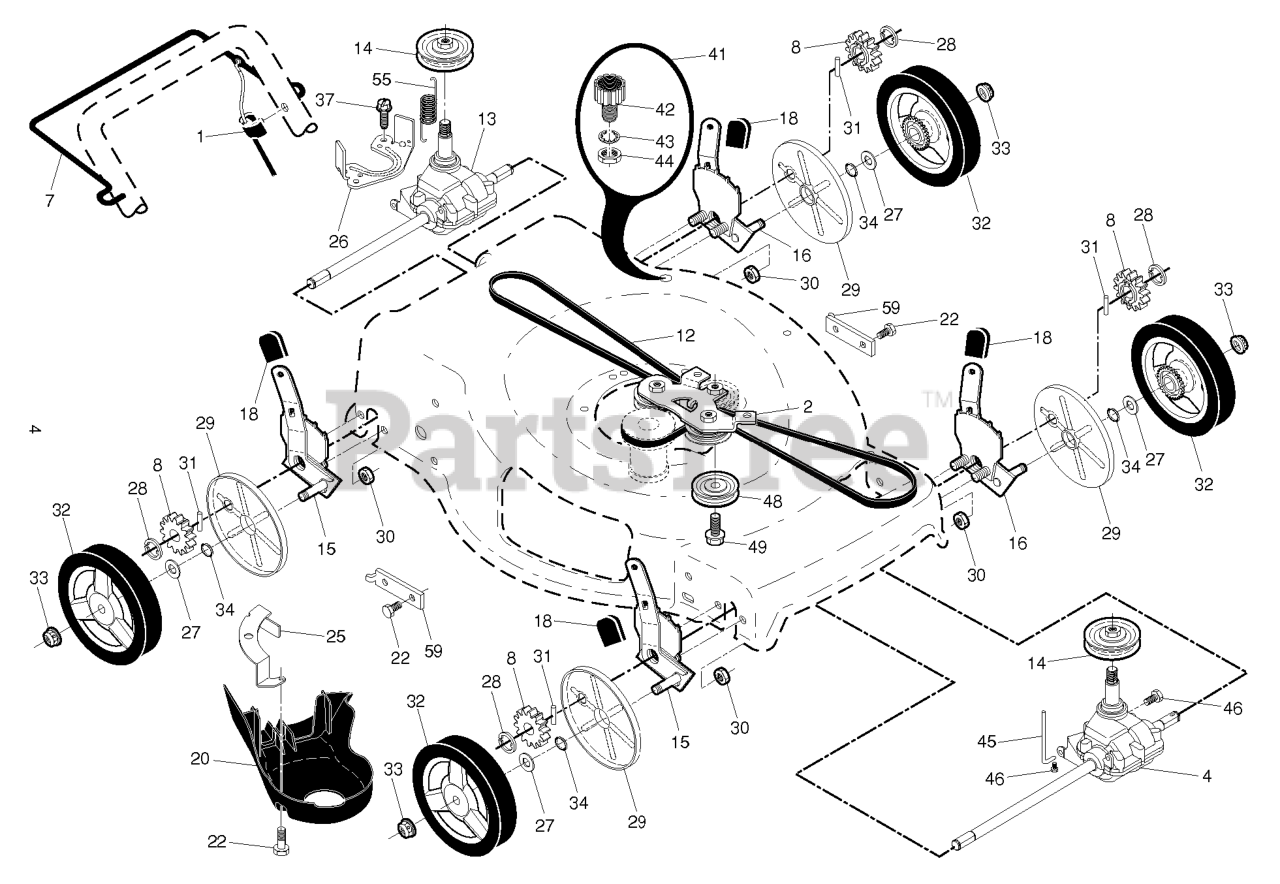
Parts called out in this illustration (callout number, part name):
1	CABLE.DRIVE.UB.AWD
2	BRACKET.ASM.AWD.BZP.BLACK
4	RP.TRANSMISSION.22+.AWD.FRONT
7	BAIL.CONT.DR.S/S.ROUND.BLACK
8	PINIION.14.TOOTH.RGD
12	BELT.DRIVE.AWD.PLUS.13
13	TRANSMISSION.22+AWD.WALK.MOWER
14	RP PULLEY.PM.22+AWD
15	RP_ADJUSTER.ASM.9.22+/RF/LR.21
16	RP ADJ.ASM.9.22+/LF/RR.21/RF
18	SELECTOR KNOB
20	COVER.REAR.DRIVE.22+2013
22	BOLT.5/16HEX.WHS.HD
25	BRACKET.DRIVE.COVER.RGD.BZP
26	BRACKET.TRAN.BELTKEEPER.22+RGD
27	WASHER FLUT
28	E-RING 7/16 RE
29	COVER.DUST.WHEEL.INNER.WALK
30	NUT.FLANGE.1-4-20-SERR
31	PAWL, DRIVE
32	WHEEL.8".AWD.3SP.EXT.DR.GREY
33	NUT.HEX.FLANGE.3/8-16.LO(3 2)
34	O-RING..070X.487.NEOPRENE
41	KIT.WASH-OUT.PORT
42	FITTING, HOSE, WATER WASHOUT
43	WASHER.LOCK.INTERNAL.TOOTH
44	LOCKNUT.HEX.WITH.O-RING
45	BRACKET.AWD.FRONT.BELT.KEEPER
46	SCREW.HI-LO.5/16 X.75
48	RP PULLEY.IDLER.ASM
55	SPRING.RETURN.AUTO.
59	BRACKET.SUPPORT.22+RWGD.BZP
